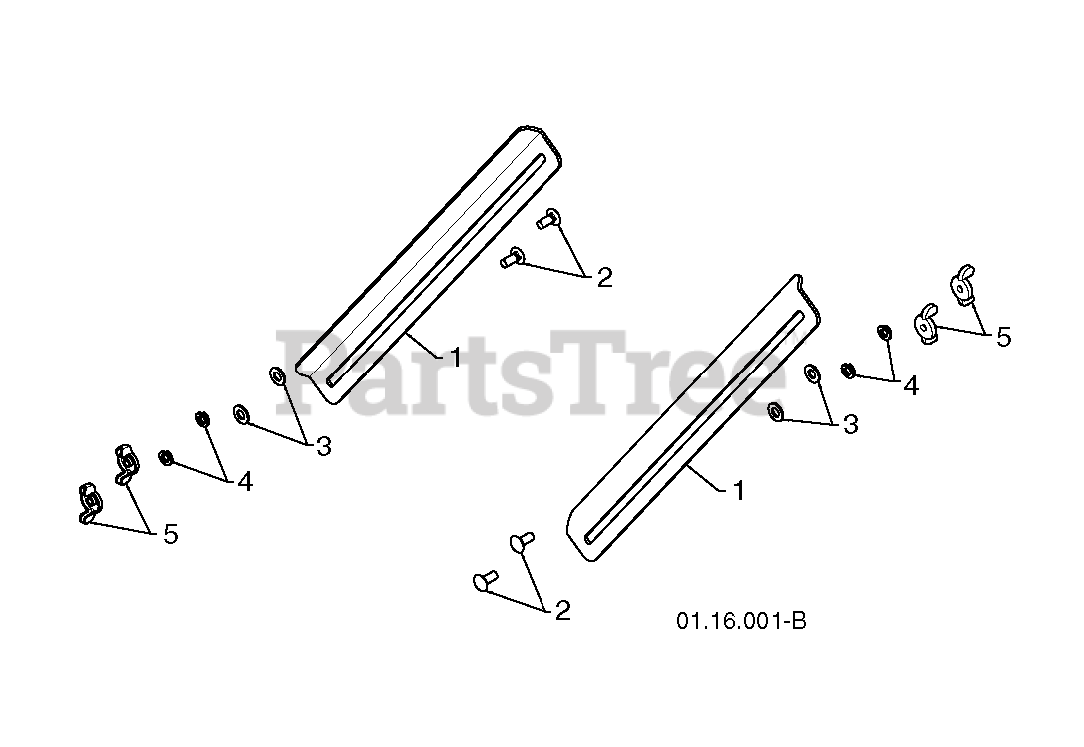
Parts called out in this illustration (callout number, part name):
1	BAR.DRIFT.CUTTER.BLACK
2	BOLT
3	WASHER, NYLON FRICTION
4	WASHER.LOCK.HVY.HLCL.SPR.5/16
5	NUT WING PM
